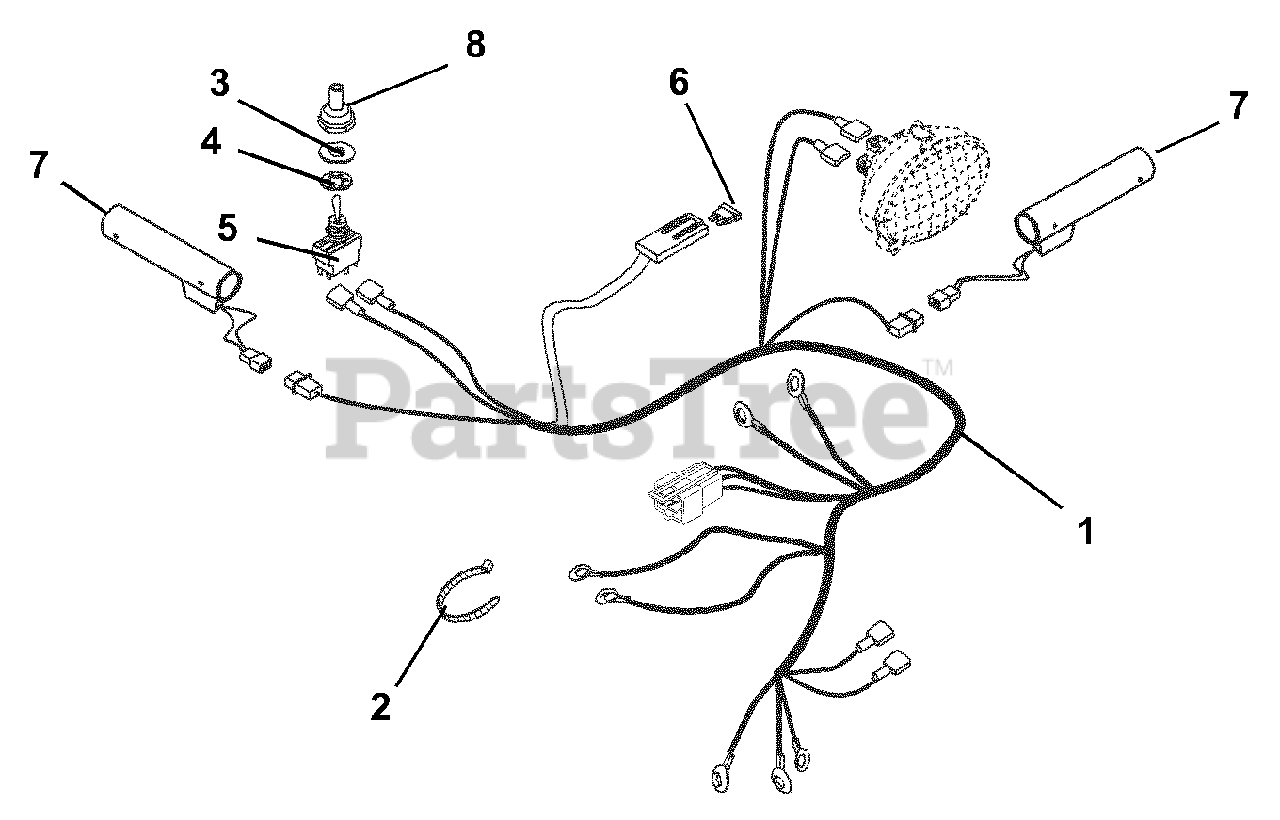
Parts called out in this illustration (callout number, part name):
1	Harness, Wiring-Light and Hand Warmer
2	Cable Tie
3	Washer, Flat Steel .51 x .88 x .024
4	Washer, Locking Internal .56 x .04
5	Switch, On/Off Hand Warmer
6	15 AMP Fuse
7	Hand Warmer with Terminal
8	Boot, Switch
